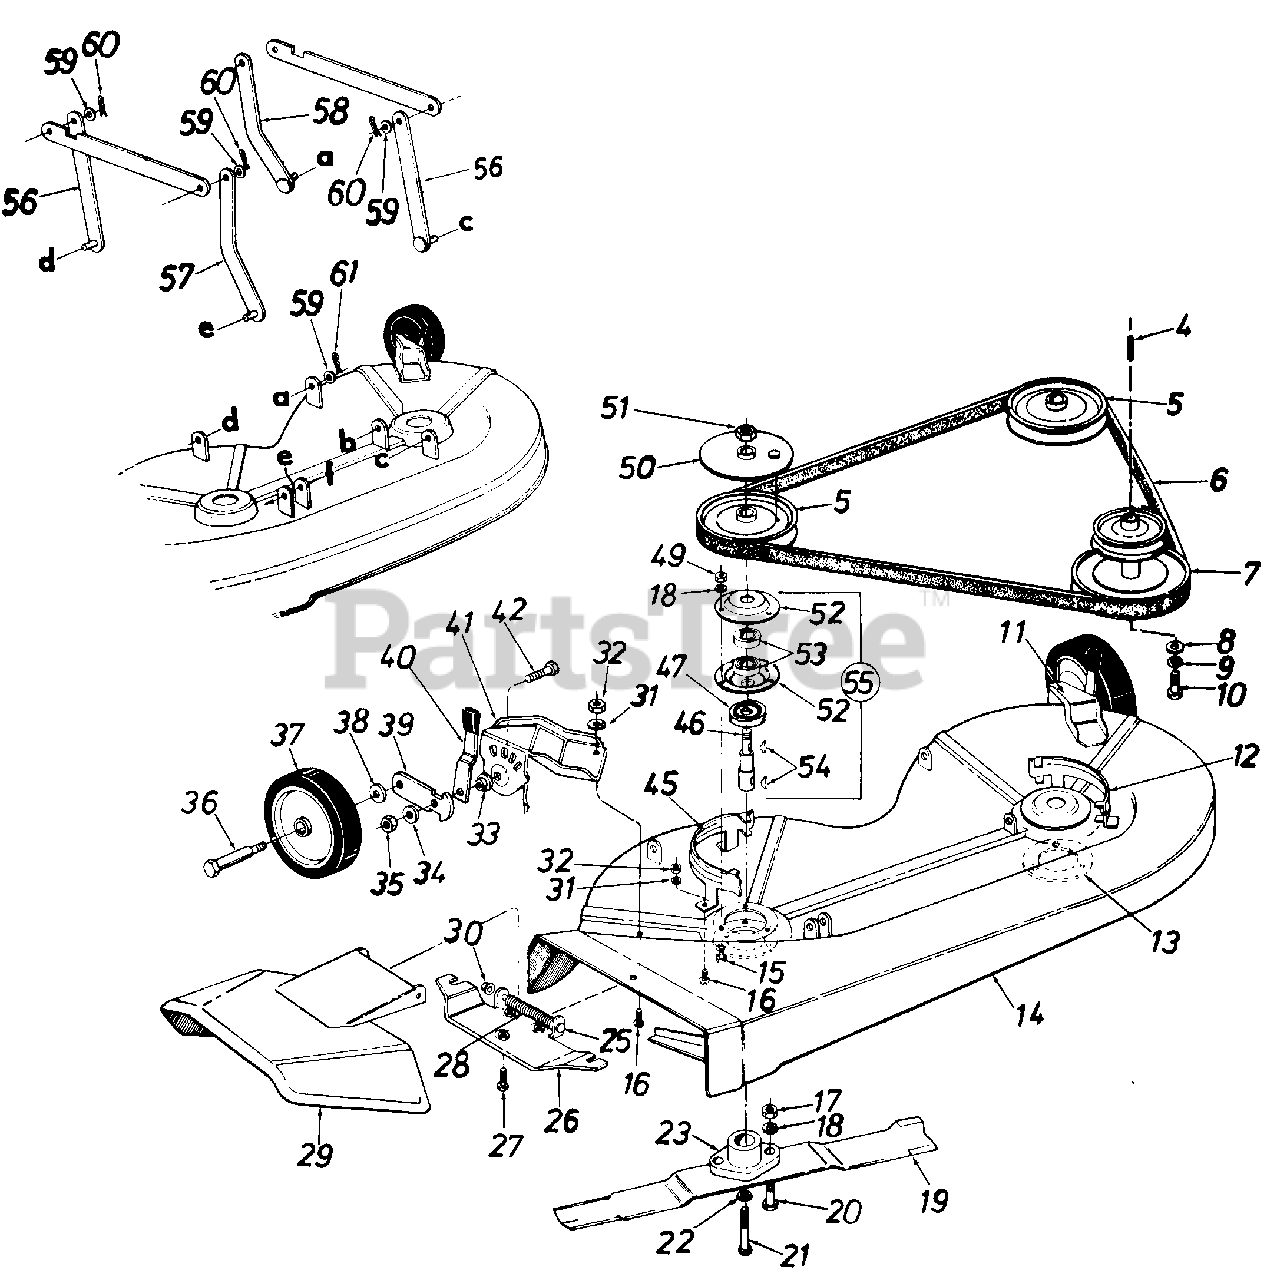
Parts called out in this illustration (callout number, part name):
4	Sq. Key 1/4" x 1/4" x 2.0" Lg.
5	Pulley 4.75" O.D.
6	"V"-Belt 21/32 x 67" Lg.
7	See Lawn Tractor Manual
8	Fl-Wash. 7/16" I.D. x 1.25 O.D. x .180
9	L-Wash. 7/16" I.D.
10	Hex Bolt 7/16-20 x 1.50" Lg.*
11	Wheel Brkt.-L H
12	Belt Guard-L.H.
13	Plate Deck Reinforcement
14	34" Deck Ass'y.
15	Hex Sems Bolt 5/16-18 x 1.00" Lg.
16	Hex Bolt 1/4-20 x .50" Lg.
17	Hex Nut 5/16-24 Thd.
18	L-Wash. 5/16" I.D.
19	17" Blade
20	Hex Bolt 5/16-24 x 1.00" Lg. (Grade 5)
21	Hex Bolt 3/8-24 x 1.50" Lg. (Grade 5)
22	L-Wash. 3/8" I.D.
23	Blade Adapter Kit
25	Hinge Pin
26	Adapter Plate
27	Hex Wash. Self-Tap Scr. 1/4-20 x .50" Lg.
28	Torsion Spring
29	Chute Cover Ass'y.-Comp.
30	Push Nut 1/4" Rod
31	L-Wash. 1/4" I.D.
32	Hex Nut 1/4-20 Thd.
33	Shld. Spacer
34	Bell-Wash. .400" I.D. x 1.13"
35	Hex Top L-Nut 3/8-16 Thd.
36	Shld. Bolt .498" Dia. x 1.53"
37	Plastic Wheel 5.0" x 1.38"
38	Bell-Wash. .400" I.D. x .88"
39	Pivot Bar
40	Spring Lever Ass'y. w/Knob
41	Wheel Brkt.-R.H.
42	Hex Bolt 3/8-16 x 1.00" Lg.
45	Belt Guard-R.H.
46	Blade Spindle
47	Bearing Shield
49	Hex Nut 5/16-18 Thd.
50	Brake Disc
51	Hex Jam L-Nut 5/8-11 Thd.
52	Bearing Housing
53	Ball Bearing .787" I.D. x 1.85" O.D.
54	#6 Hi-Pro Key 5/32" x 5/8" Dia.
55	Blade Spindle Ass'y.
56	Link Deck Hanger Ass'y.
57	Link Deck Hanger Ass'y.
60	Inter. Cotter Pin 3/8" Dia.
61	Inter. Cotter Pin .50" Dia.
